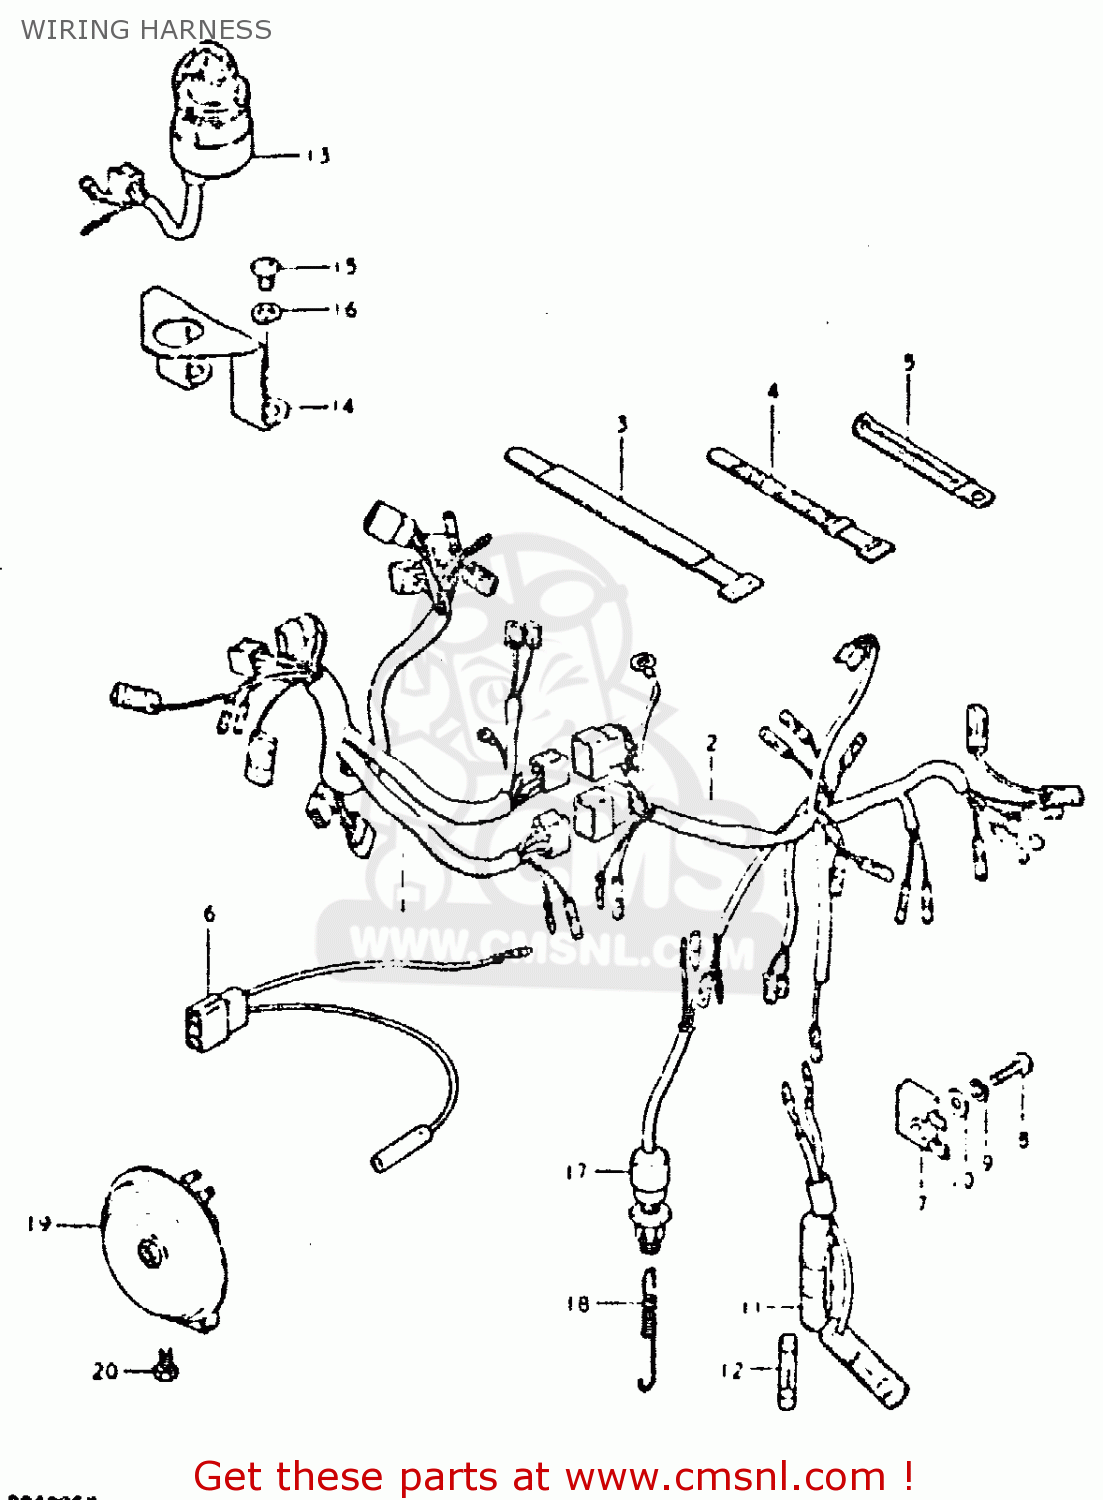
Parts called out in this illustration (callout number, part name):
1	WIRING HARNESS NO. 1
2	WIRING HANRESS NO. 2
3	CLAMP
4	CLAMP(L:120)
5	CLAMP L:35
6	WIRE
7	RECTIFIER ASSEMBLY
8	SCREW 5X20
9	LOCK WASHER
10	WASHER
11	BOX ASSEMBLY,FUSE
12	FUSE(15A)
13	SWITCH ASSY, IGNITION
14	BRACKET,IGNITION SWITCH
15	SCREW
16	LOCK WASHER
17	SWITCH ASSEMBLY,STOP LAMP
18	SPRING
19	HORN ASSY
20	BOLT
